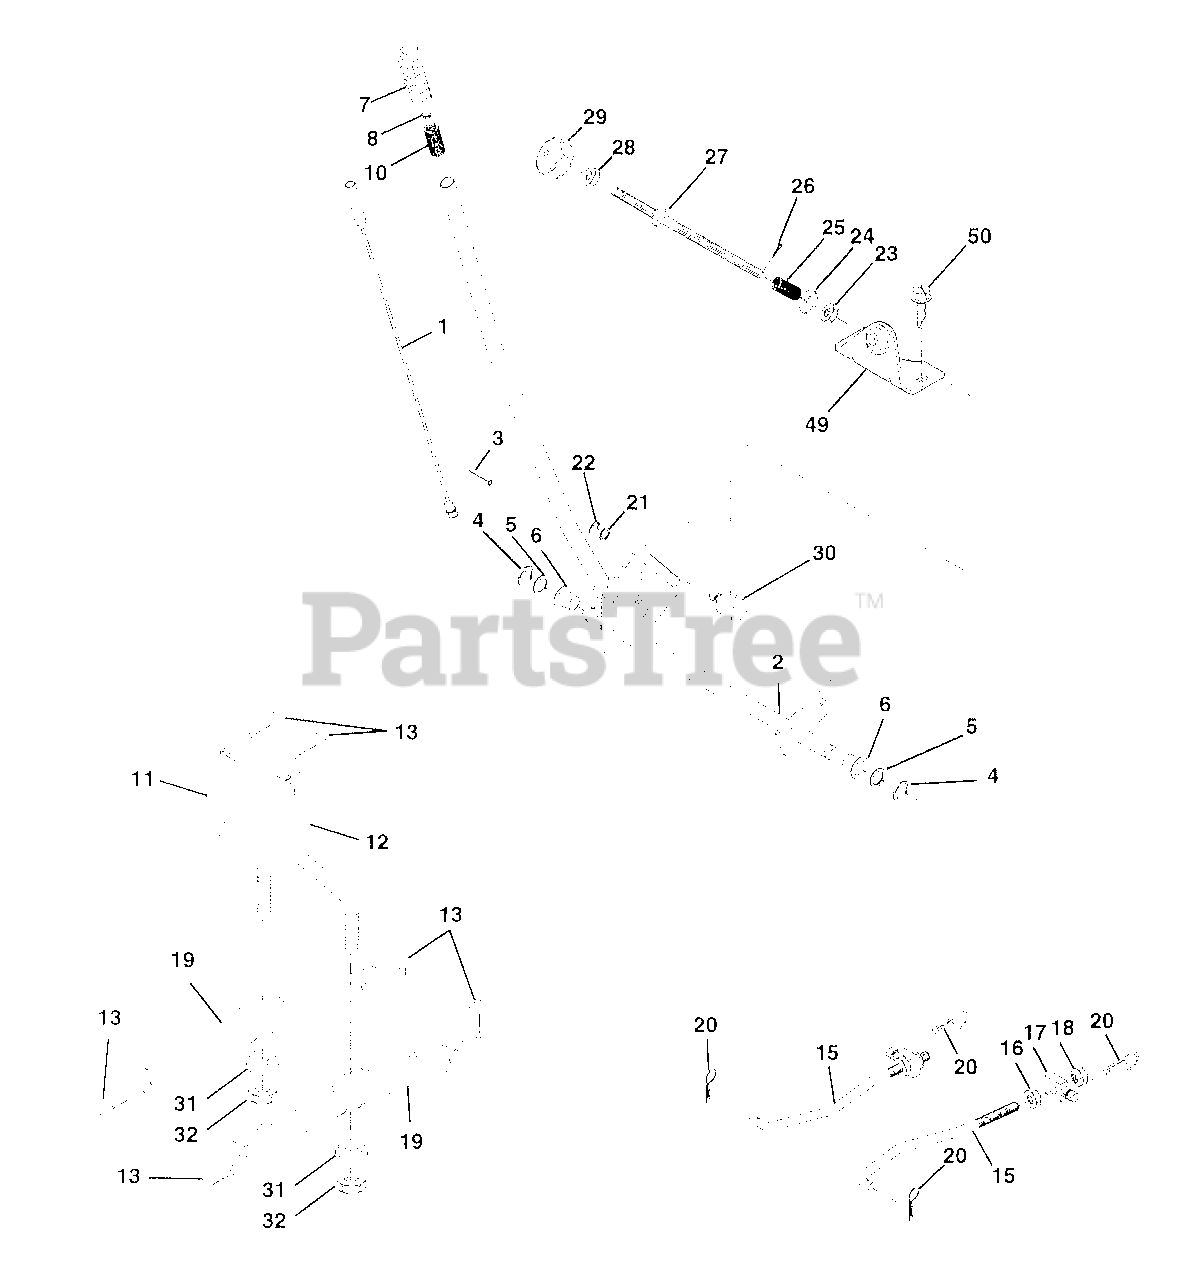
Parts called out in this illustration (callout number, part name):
1	Wire Asm Inner w/plunger
2	Shaft Asm Lift LH Inf Hgt P/L
3	Pin Groove
4	E Ring #5133-62
5	Washer PLTD 21/32 X 1 X 21ga
6	Bearing Nylon Blk 629 Id
7	Grip Handle Bicycle Matte Blk
8	Button Plunger Black
10	Spring Cprsn 3 750 Oiled
11	Link Lift LH
12	Link Lift RH
13	Retainer Spring
15	Link Front
16	Nut Jam Hex 1/2-13 Unc
17	Trunnion Blk Zinc
18	Nut Lock W/wsh 1/2-13unc
19	Arm Suspension Rear
20	Retainer Spring
21	Washer 15/32 X 3/4 X 16ga
23	Nut Special
24	Washer 13/32 x 5/8 x 16 ga
25	Spring 2-1/8
26	Pin Cotter 3/32 x 1/2
27	Rod Adj Lift
28	Nut Hex Jam 3/8-16 Unc
29	Knob Inf 3/8-16 UNC
30	Trunnion Dp Stop
31	Bearing Pivot Lift Spherical
32	Nut Lock 3/8-24 w/nylon Insert
49	Bracket Stop Inf Hgt
50	Screw Thdrol 3/8-16 x 1/2
